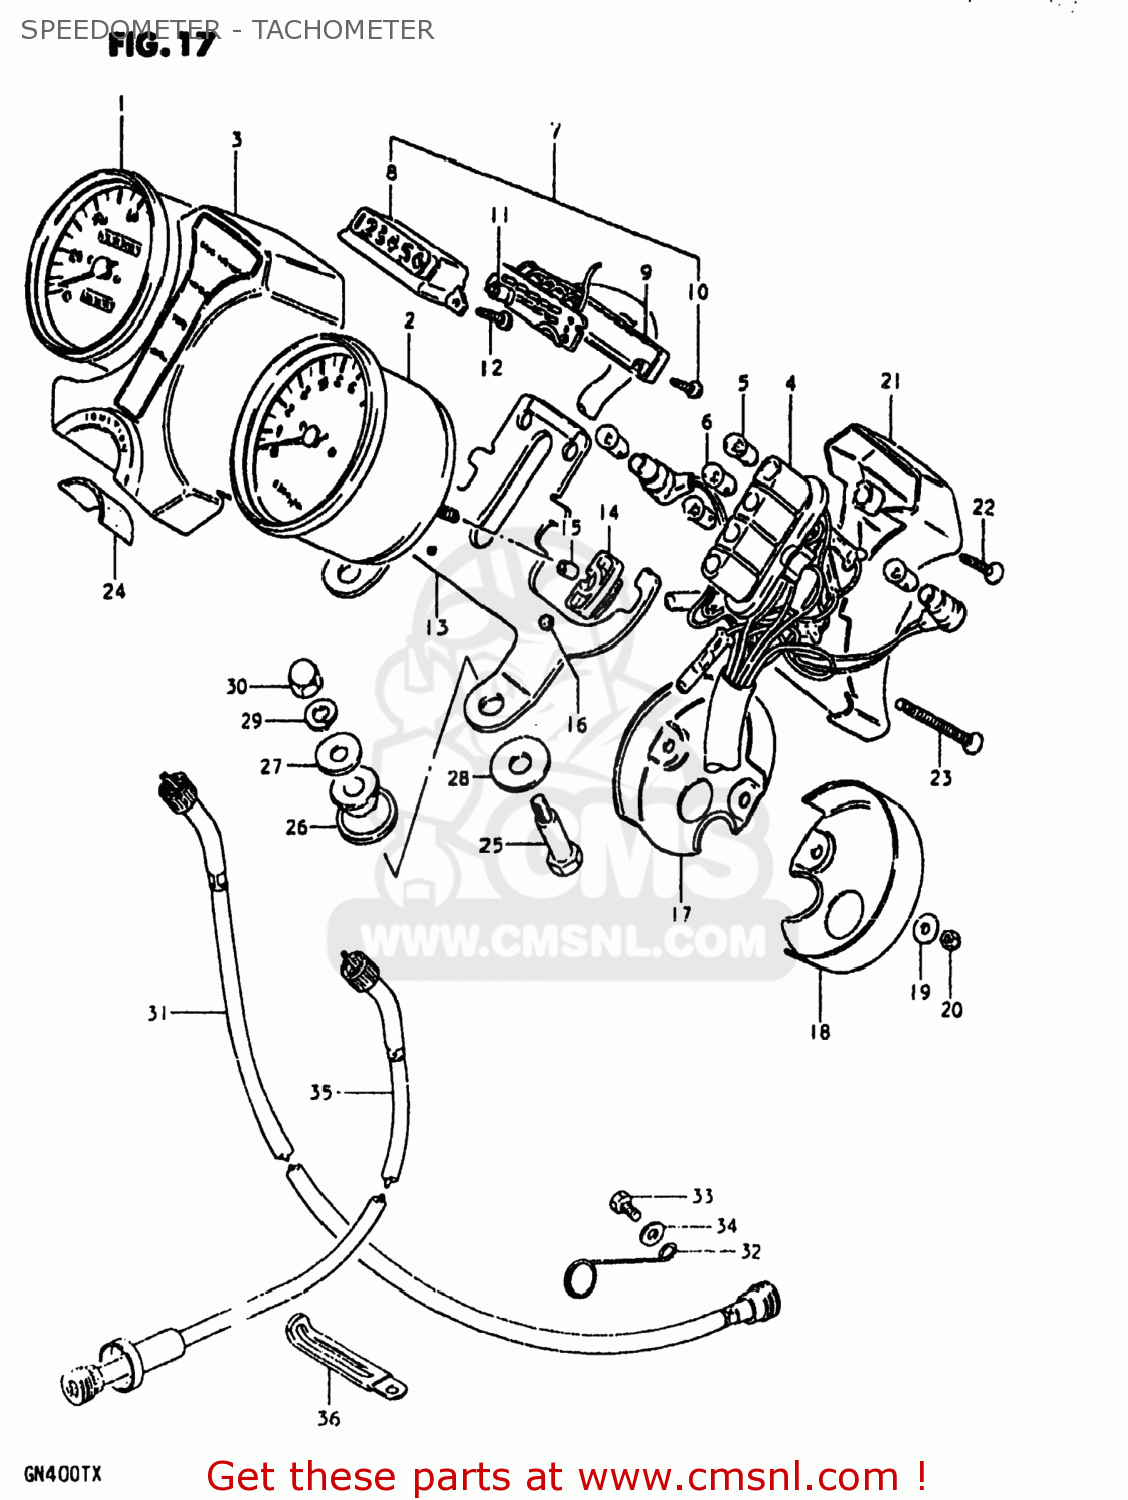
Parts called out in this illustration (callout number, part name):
1	SPEEDOMETER ASSEMBLY
2	TACHOMETER
3	CASE,PILOT BULB
4	SOCKET,METER
5	BULB(6V/3W)
6	BULB(6V1.7W,STANLEY,A61A)
7	INDICATOR ASSEMBLY,GEAR
8	CASE,GEAR INDICATOR
9	COVER,LWR
10	SCREW,GEAR INDICATOR
11	BULB(7V1.1W,BQ041-27503B)
12	SCREW
13	BRACKET,METER
14	CUSHION,SPEEDOMETER
15	SPACER
16	CUSHION,METER
17	COVER,METER
18	PLATE,TACHOMETER UNDER
19	WASHER
20	NUT
21	COVER,PILOT BULB CASE
22	SCREW
23	SCREW
24	SEAL,IGNITION SWITCH
25	BOLT
26	CUSHION,METER
27	WASHER(8.5X23X1.2)
28	WASHER
29	LOCK WASHER
30	NUT
31	CABLE ASSEMBLY,SPEEDOMETER
32	GUIDE,SPEEDOMETER CABLE
33	BOLT, UPPER
34	WASHER
35	CABLE ASSEMBLY,TACHOMETER
36	CLAMP L:35
